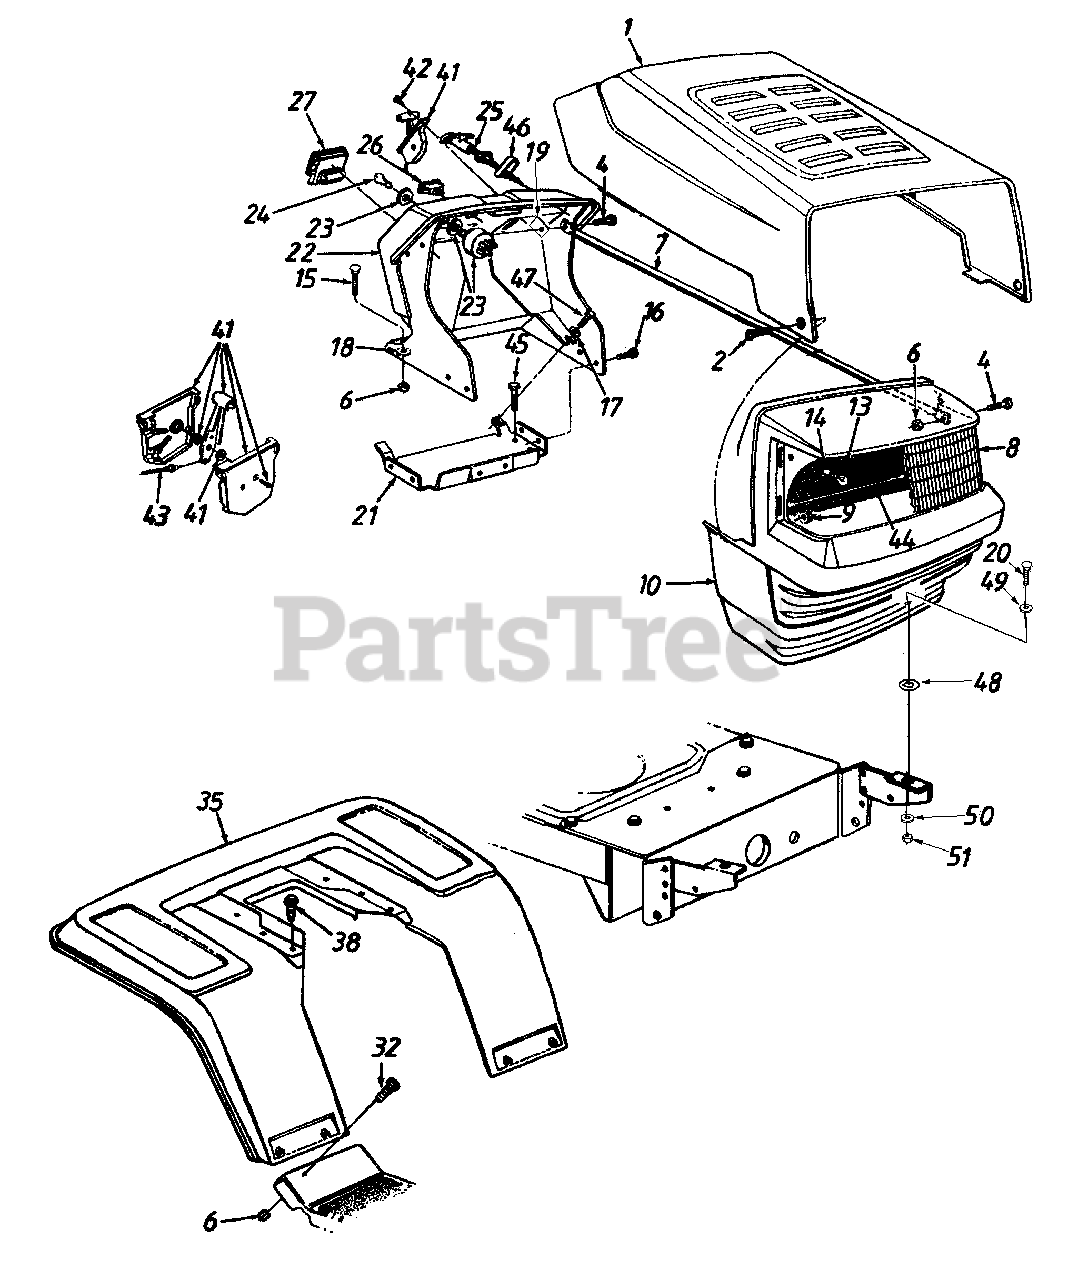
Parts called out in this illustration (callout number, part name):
4	Pan Hd. Scr.1/4-20 x .75" Lg.
6	Hex Sems Nut 1/4-20 Thd.
8	Headlight Lens w/o Logo
9	Flange L-Nut 1/4-20 Thd.
10	Grille
13	Lamp
14	Socket
15	Carriage Bolt 1/4-20 x .75" Lg.
16	Hex Wash. Hd. TT-Tap Scr. 1/4-20 x .5" Lg.
17	Fl-Wash. .281" I.D. x .73" O.D.
18	Bolt Retainer 1/4" I.D.
19	Speed Nut 1/4-20 Thd.
20	Hex Bolt 5/16-18 x .75" Lg. (Gr.5)
23	Ignition Switch
24	Ignition Key
25	Choke Control 23" Lg.
26	Light Switch
27	Ammeter
32	Truss Mach. Scr. 1/4-20 x .5" Lg.
41	Throttle Box Ass'y.
42	Truss Mach. AB-Tap Scr.#10 x .5" Lg.
43	Throttle Control Wire 18.5" Lg.
44	Grille Reflector Label
45	Hex Wash. Hd. B-Tap Scr.5/16-18 x .5" Lg.
46	Choke Retainer
47	Hex TT-Tap Scr. 1/4-20 x .75" Lg.
48	U-Nut 5/16-18 Thd.
49	Fl-Wash. .34" I.D. x 1" O.D.
50	L-Wash. 5/16" I.D.
51	Hex Nut 5/16-18 Thd. (Gr.5)
